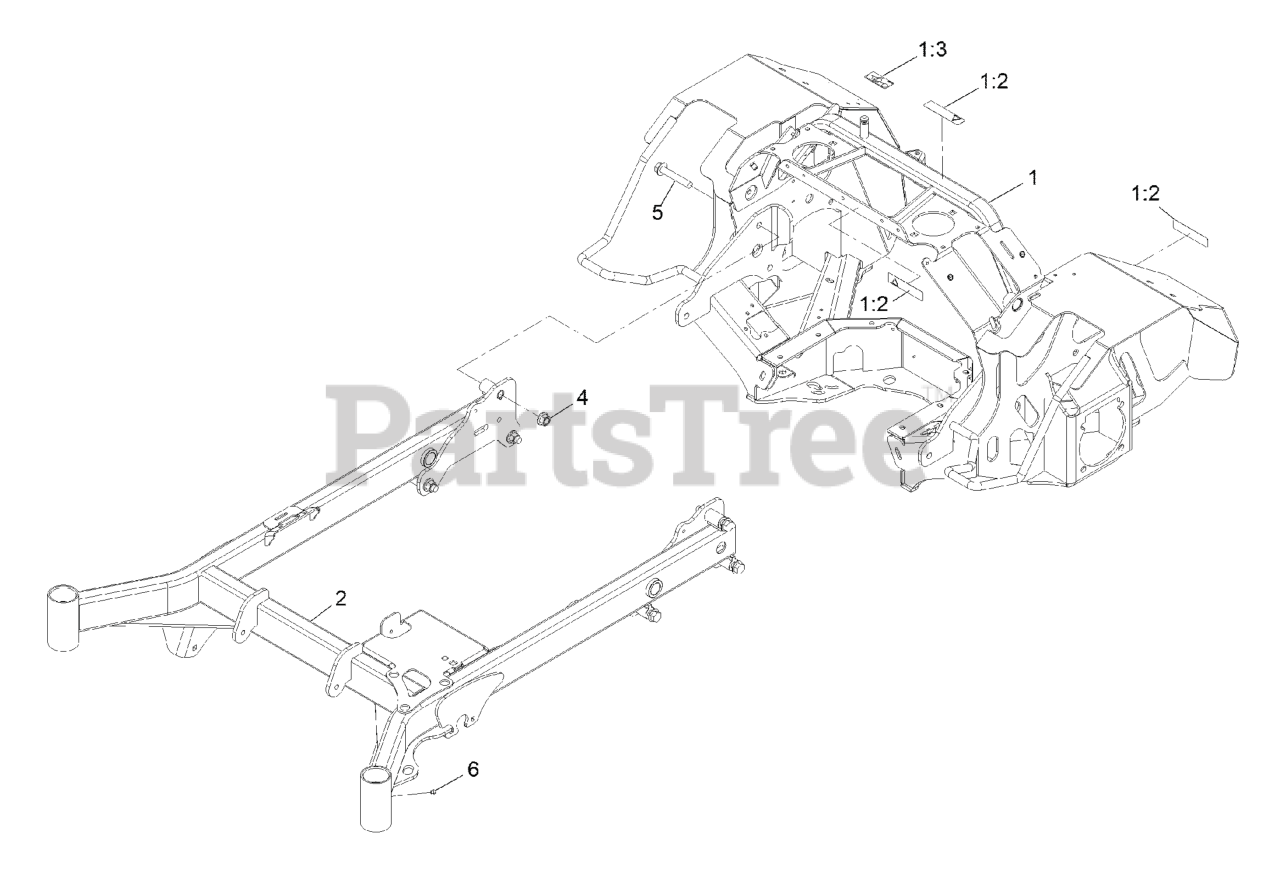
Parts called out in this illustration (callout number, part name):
1	ASM, REAR FRAME W/ DECALS
1:2	DECAL-WARNING
1:3	DECAL-BELT ROUTING HYD
2	WELD, FRONT FRAME, 48/52
4	Nut-Lock 1/2-13
5	SCREW-HF
